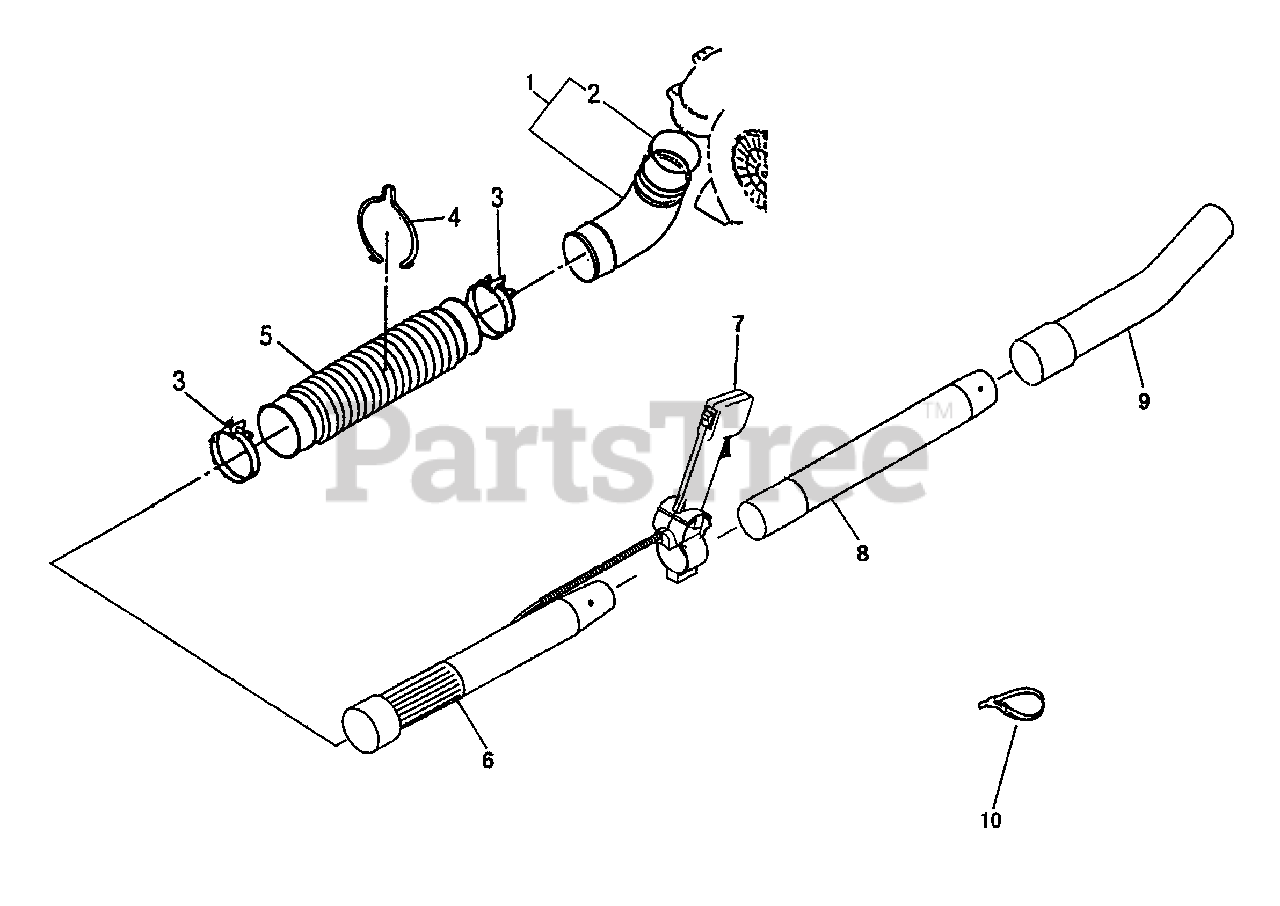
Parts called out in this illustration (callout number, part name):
1	Elbow Pipe
2	O-Ring
3	Hose Band
4	Wire Clamp
5	Flex Pipe
6	Base Pipe
7	Throttle Assy.
8	Middle Pipe
9	Bend Pipe
10	Wire Band
